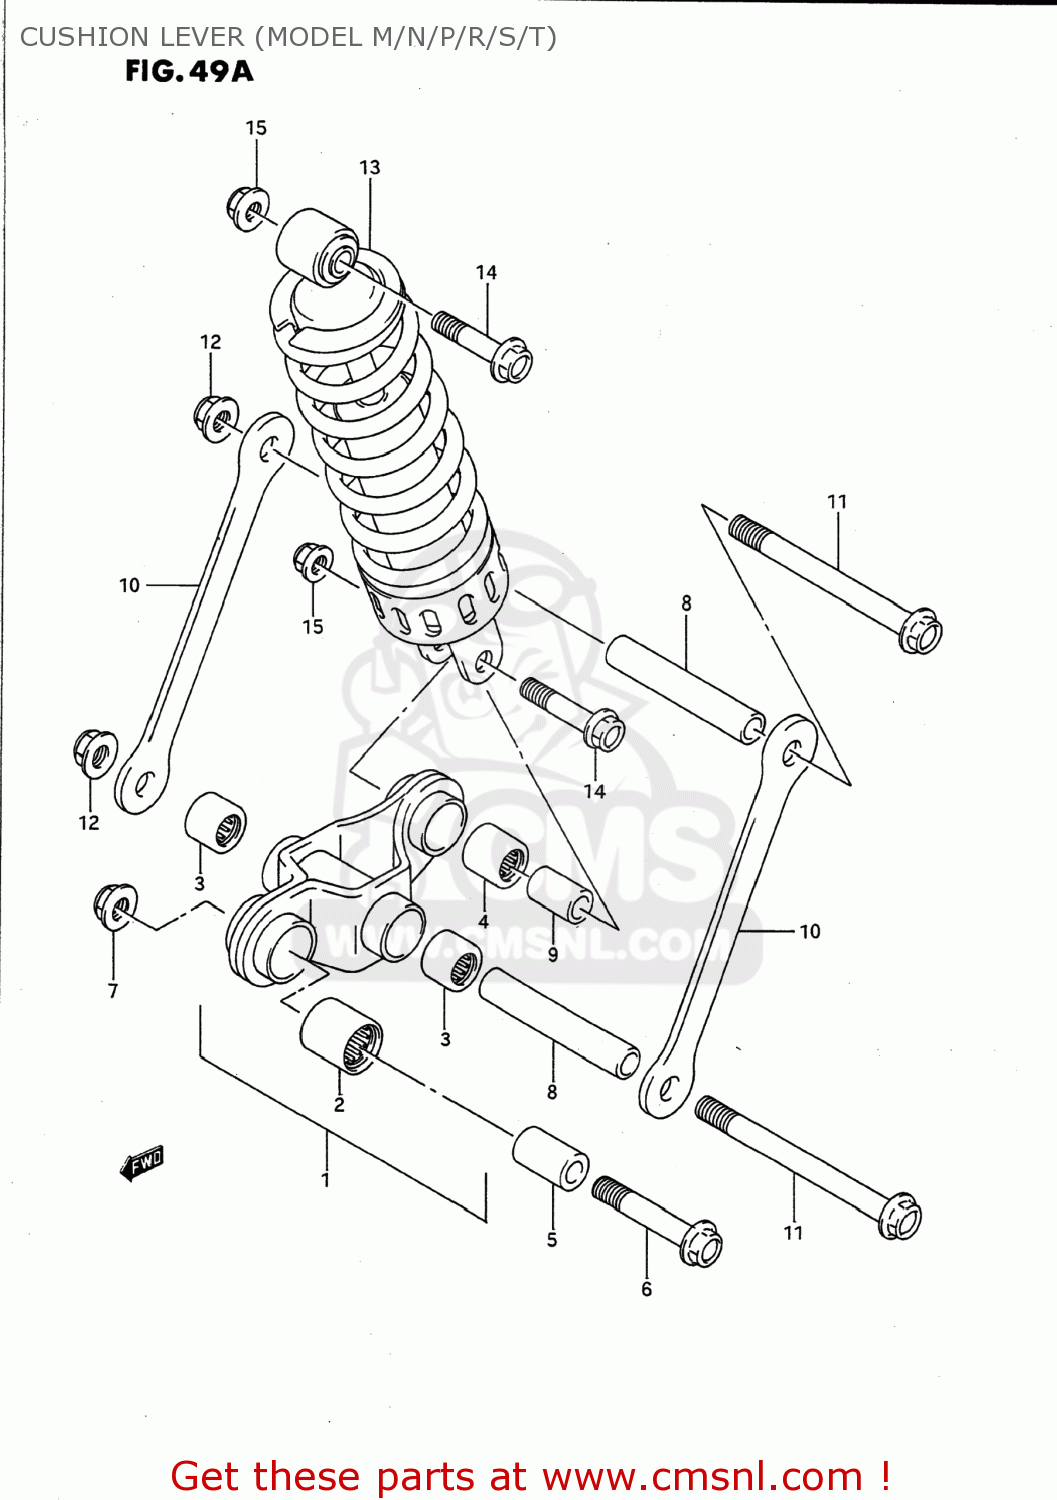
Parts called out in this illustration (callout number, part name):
1	LEVER SET,RR CUSHION
2	BEARING(20X27X26)
3	BEARING(17X24X25)
4	BEARING(17X24X26)
5	SPACER,REAR CUSHION LEVER
6	BOLT(12X57)
7	NUT 12MM
8	SPACER (12X17X89)
9	SPACER,RR CUSHION LEVER
10	ROD,RR CUSHION LEVER
11	BOLT(12X118)
12	NUT 12MM
13	ABSORBER ASSY,RR SHOCK
14	BOLT(10X52)
15	NUT
